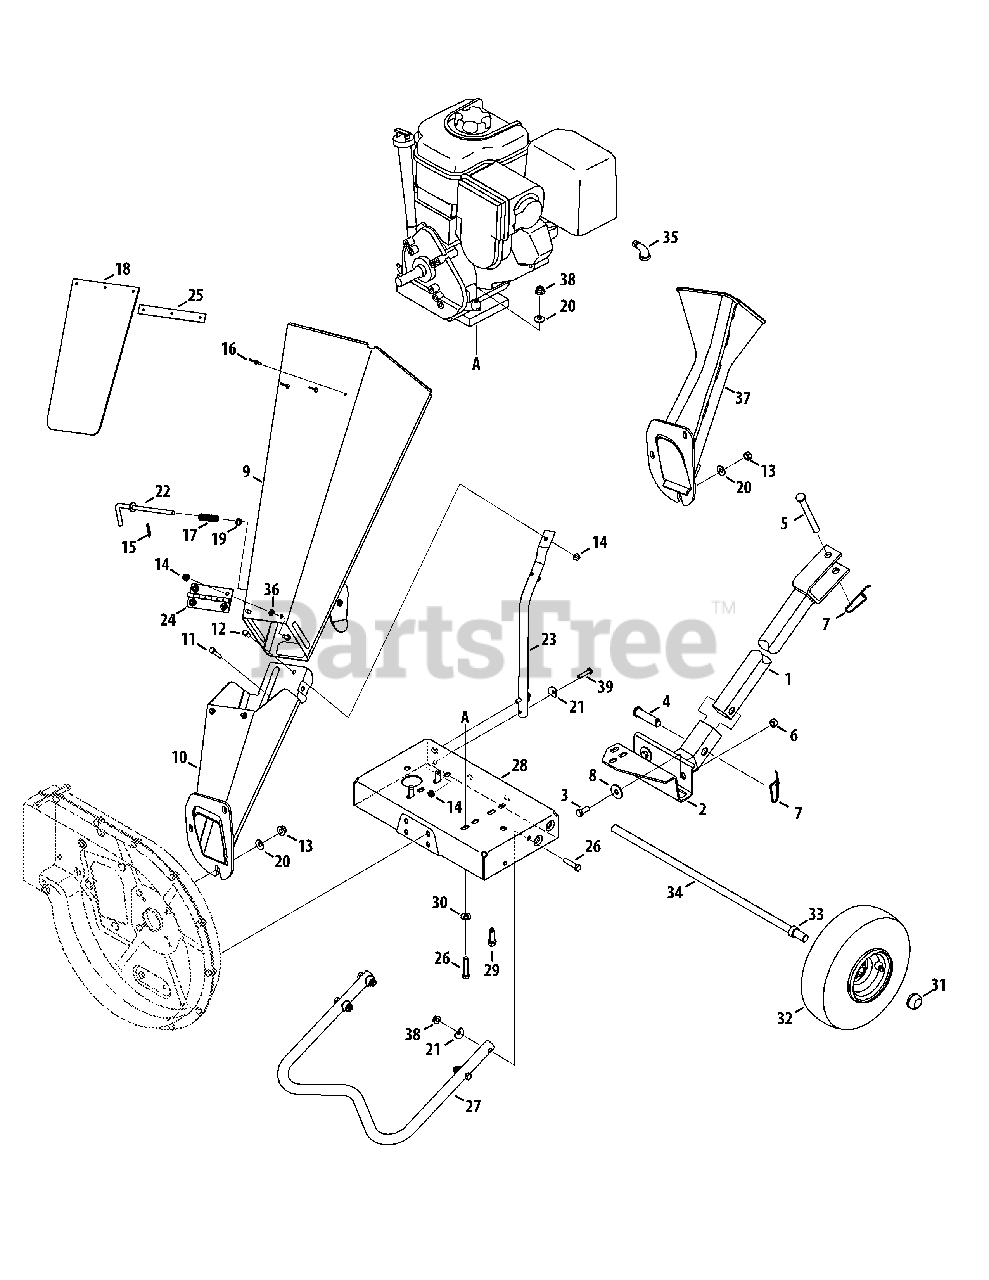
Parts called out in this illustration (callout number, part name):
1	Tongue Hitch Mount
2	Base Hitch Mount
3	Hex Cap Screw, 3/8-16 x.88
4	Clevis Pin,.625 x 2.4
5	Clevis Pin,.50 x 4.62
6	Flange Lock Nut, 3/8-16
7	Spring Pin
8	Flat Washer,.411 x 1.25 x 1.0
9	Upper Chipper Chute Assembly
10	Lower Chipper Chute Assembly
11	Hex Cap Screw, 1/4-20 x 1.25
12	Screw, 1/4-20 x .50
13	Hex Nut, 5/16-18
14	Flange Lock Nut 1/4-20
15	Cotter Pin
16	Pop Rivet
17	Compression Spring,.531 x 1.75
18	Chute Flap
19	Flat Washer
20	Bell Washer.340 ID x.872 OD
21	Washer,.320 ID x.93 OD
23	Chipper Chute Support
24	Chipper Chute Hinge
25	Chute Flap Strip
26	Hex Cap Screw, 5/16-18 x 1.50
28	Frame Assembly
29	Hex Sems Screw, 3/8-16 x 1.25
30	Special Lock Washer, 5/16
31	Push Cap, 5/8
32	Wheel, 10 x 4 x 4
32	Flange Bearing
32	Flange Bearing w/fitting
33	Spacer, .64 x .88 x .38
34	Axle, 22.47"
35	Elbow Fitting
36	Push Nut,.25ID x.50OD
37	Chipper Chute
38	Flange Lock Nut, 5/16-18
39	Hex Cap Screw, 1/4-20 x 1.250
